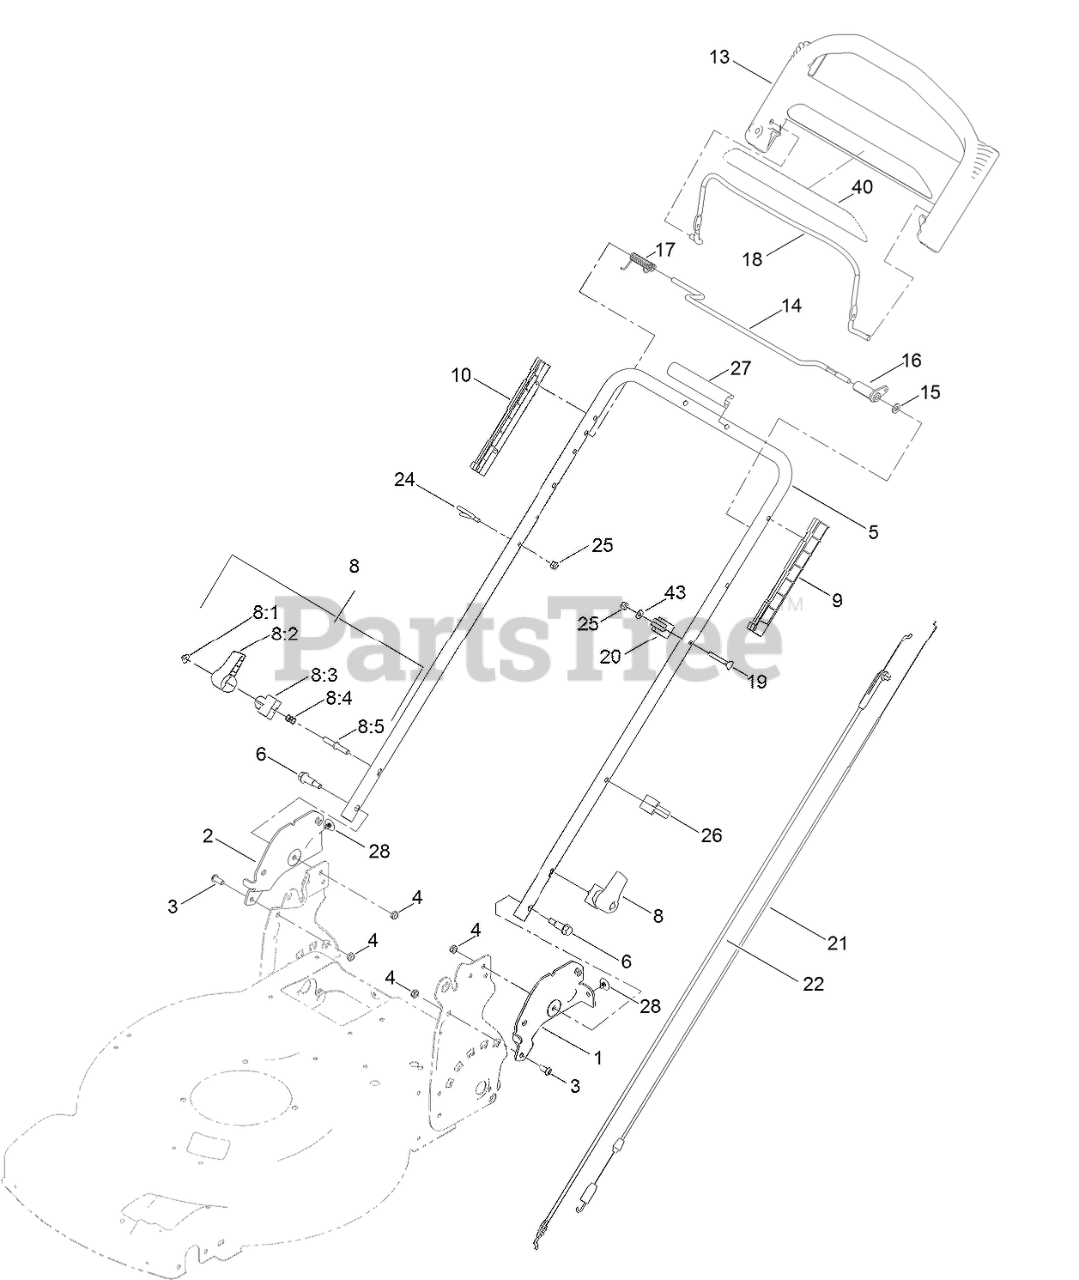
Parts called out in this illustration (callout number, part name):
1	PLATE-HANDLE, LH
2	PLATE-HANDLE, RH
3	SCREW-HSBH
4	NUT-HEX
6	BOLT-SHOULDER
8	QUICK RELEASE ASM
8:1	NUT-PUSH
8:2	LEVER-RELEASE
8:3	ANCHOR-SPRING
8:4	SPRING-COMPRESSION
8:5	ROD-RELEASE
9	GUIDE-LH
10	GUIDE-RH
13	HANDLE-CONTROL
14	BAR-CONTROL, TRACTION
15	WASHER-PLAIN
16	LEVER-TRACTION
17	SPRING-TORSION
18	BAIL-BRAKE
19	BOLT-CARR
20	ANCHOR-CABLE
21	CABLE-TRACTION
22	CABLE-BRAKE
24	GUIDE-ROPE
25	NUT-HEX
26	GUIDE-CABLE
27	HANDLE-COVER
28	CLIP-TREE
43	WASHER-FLAT
